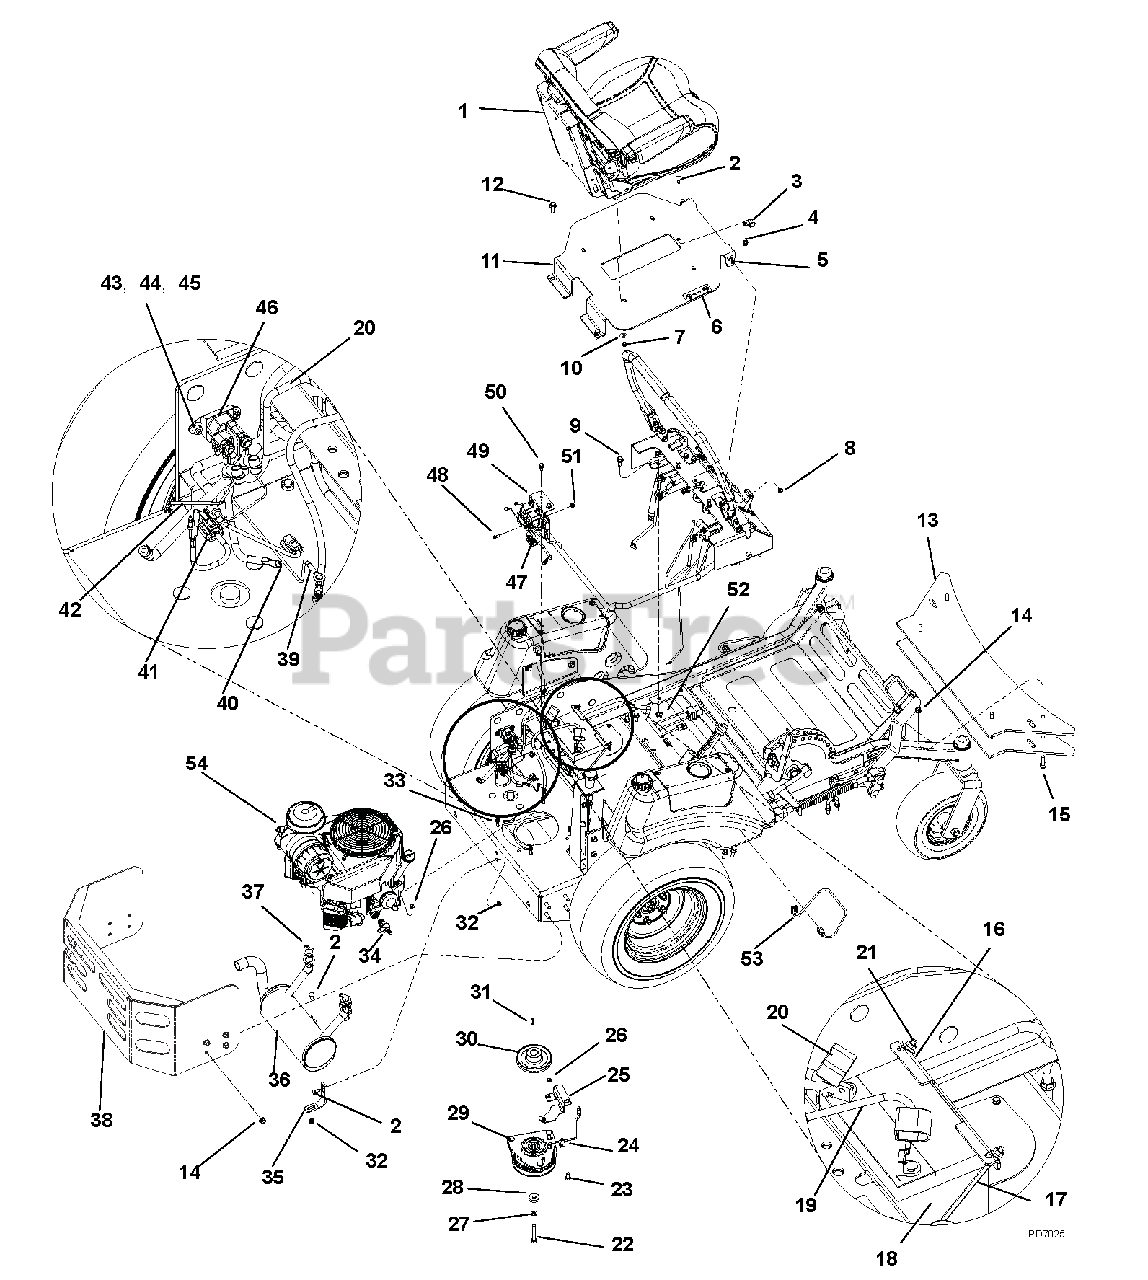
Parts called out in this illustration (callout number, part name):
1	SEAT, FULL SUSPENSION, NO LOGO
2	BOLT, M8X1.25X20 CRG 8.8 Y
3	P-CLIP, .750 INSULATED
4	LOCKNUT, M8X1.25 NYLOC FLG 10Y
5	BOLT, 1/2X1.06X3/8-16 SLD 5 Y
6	LABEL - PARK BRAKE DIRECTION
7	LOCKNUT, 5/16-18 NYLOC Y
8	NUT, 3/8 LOCK
9	SCREW,HEX,FL,JDS123,M10X1.5X25
10	WASHER, .344X1.00X.134 FLAT Y
11	PLATE, SEAT GD
12	SCREW,HEX,FL,JDS123,M10X1.5X30
13	PLATE, WEIGHT BLK
14	LOCKNUT,FL,ISO7044,M10X1.5-10-
15	SCREW,HEX,FL,JDS121,M10X1.5X40
16	HOLDER, BATTERY
17	J BOLT
18	BATTERY, 12V-U1-CCA400MIN
19	CABLE, BATTERY - 20" GROUND
20	CABLE, BATTERY POSITIVE
21	NUT-1/4" FLANGE PREVAILING TOR
22	BOLT, 7/16-20X2.75 HEX 5 Y
23	BOLT, 7/16-14X.750 HEX 5 Y
24	CABLE TIE, .31 X 14.6 - BLACK
25	PLATE, CLUTCH DOG
26	LOCKNUT, 5/16-18 CROWN Y
27	WASHER, .438 MED SPRG LOCK Y
28	SPACER, .468 X 1.38 X .375 Y
29	CLUTCH ASSY, OGURA# GT1A-HU02
30	PULLEY, V-BELT 4.78PD X 1.000
31	KEY, .250 X .250 X .995 TPR
32	LOCKNUT,M8X1.25,FLANGED ZN
33	BOLT, 5/16-18X1.75 HEX 5 Y
34	FITTING, OIL DRAIN #
35	BRACKET, MUFFLER
36	MUFFLER, CHARIOT ACS KAI
37	GASKET, MUFFLER
38	BUMPER, REAR GDKW
39	WIRE, GROUND
40	CABLE, 12" STARTER
41	HARNESS, PIGTAIL
42	FUSIBLE LINK, 10"
43	BOLT, 1/4-20X.750 HEX 5 Y
44	LOCKNUT, 1/4-20 CENTER Y
45	MANUAL,OWNERS RAPID XZ TRACTOR
46	SOLENOID
47	RELAY, SEALED W/BRACKET
48	SCREW,FL,JDS123,M6X1X16-10.9-Z
49	BRACKET, ELECTRIC MOUNTING
50	SCREW,HEX,FL,JDS123,M8X1.25X16
51	LOCKNUT,FL,ISO7043,M6X1.00-10-
52	LOCKNUT, M10X1.50 WHIZ GR10 Y
53	HARNESS, WIRING
54	ENGINE, KAWASAKI 19HP FH580V
